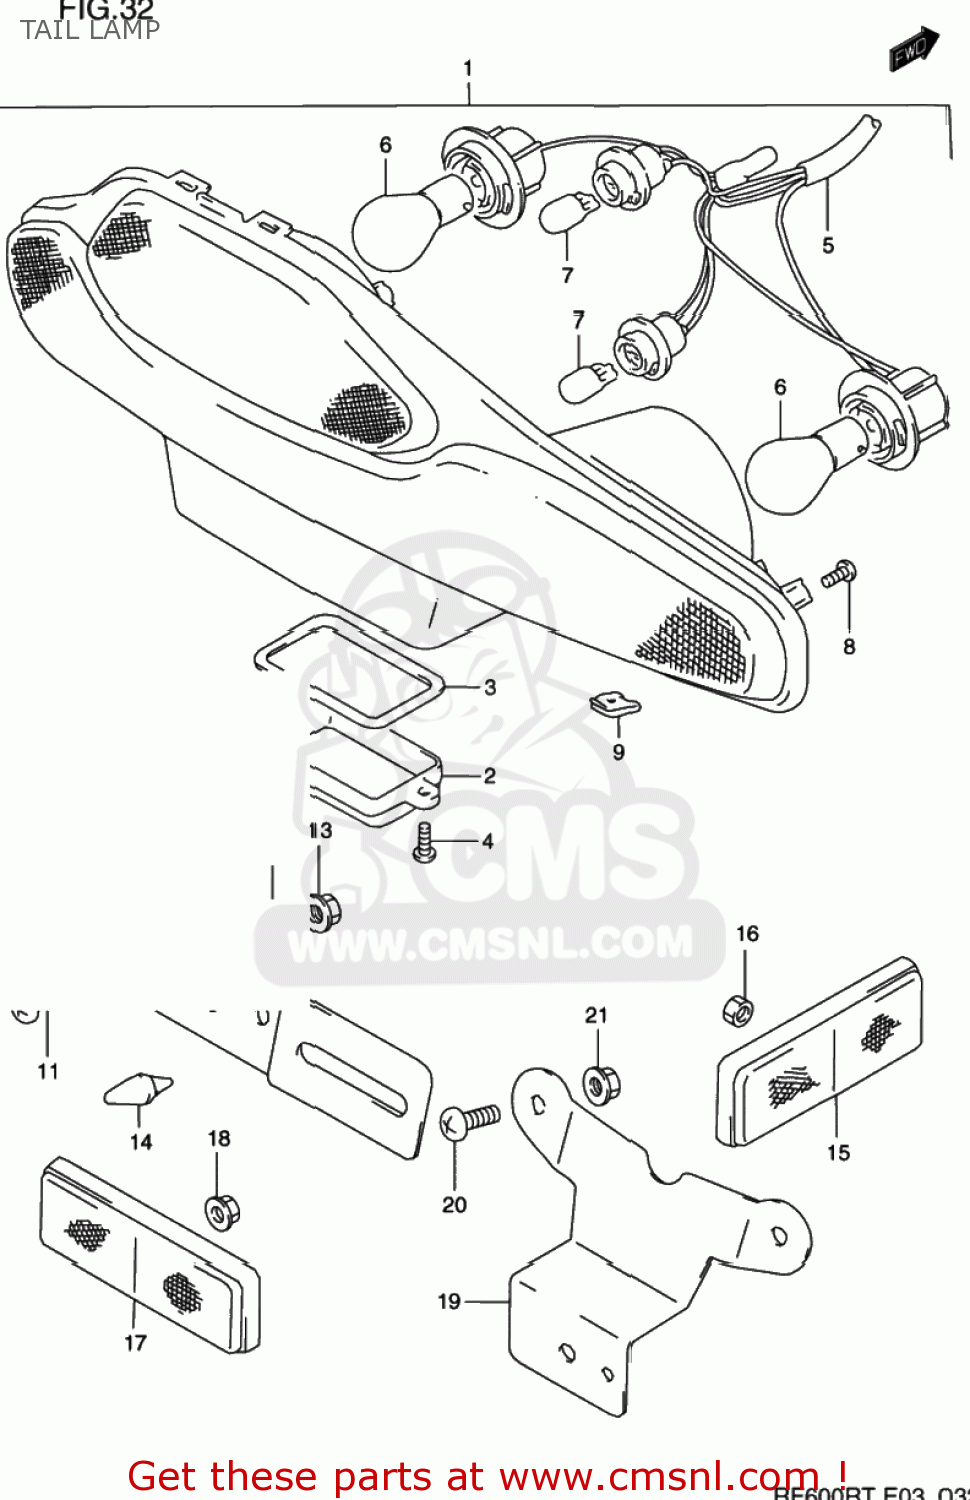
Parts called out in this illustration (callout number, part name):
1	LAMP ASSY,RR COMBINATION
2	LENS,LICENSE LAMP
3	GASKET (NAS)
4	SCREW
5	SOCKET & CORD
6	BULB(12V21W)
7	BULB(12V5W)
8	SCREW
9	NUT
10	BRACKET,LICENSE PLATE
11	SCREW 6X12
12	WASHER,COVER,FRONT
13	NUT
14	CUSHION
15	REFLECTOR ASSY,RR
16	NUT
17	REFLECTOR ASSY,RR
18	NUT
19	BRACKET,RR REFLECTOR
20	SCREW 6X12
21	NUT
